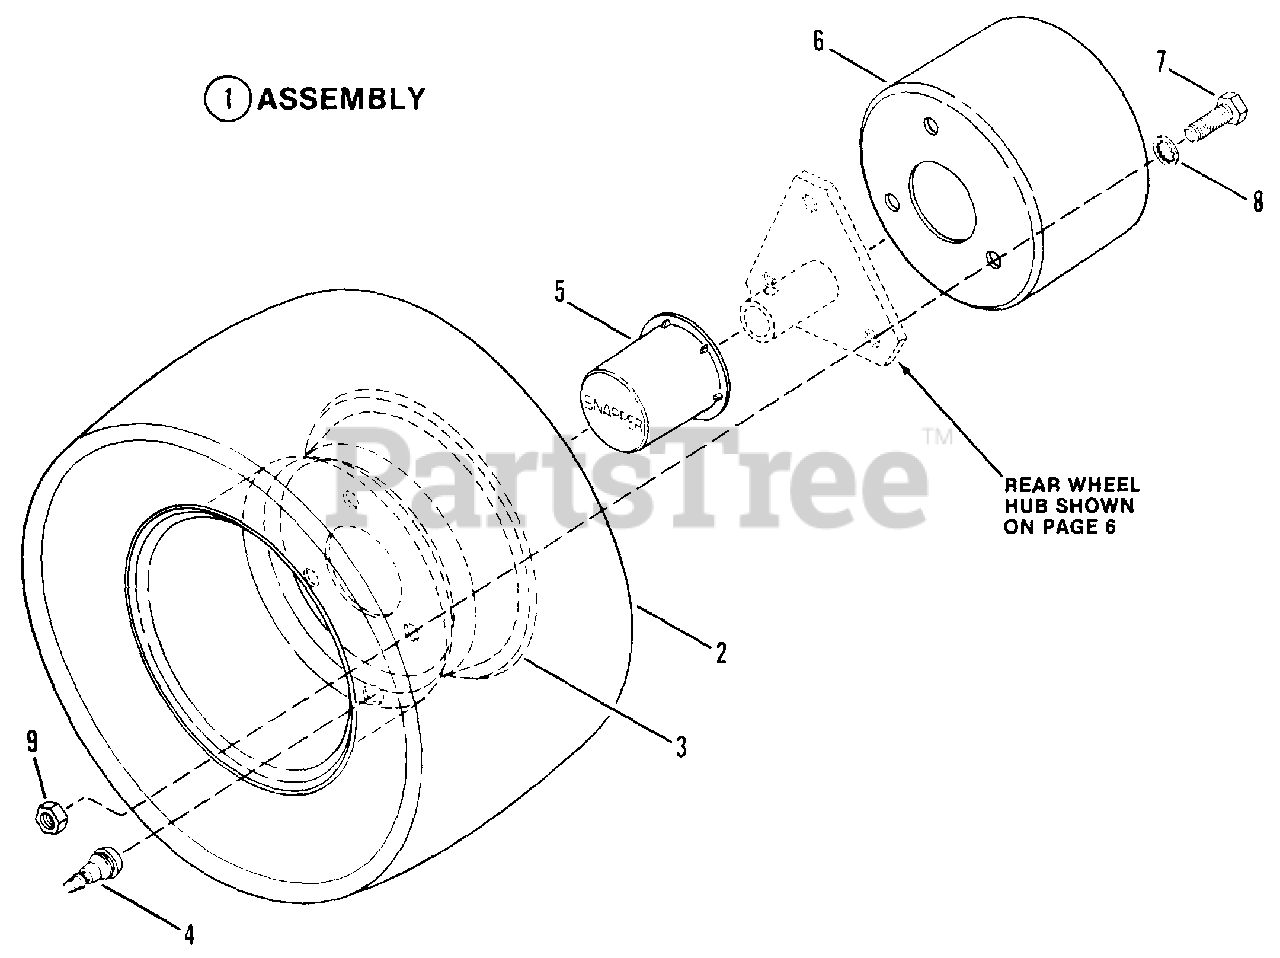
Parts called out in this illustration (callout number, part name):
1	ASSEMBLY, Rear Tire & Rim
2	TIRE, Wide, 16/6.50 x 8
3	RIM, Wide
4	VALVE, Air
5	HUB-CAP
6	BRAKE DRUM
7	SCREW, 1/2-20 x 1-1/4" Hex Head Cap
8	WASHER, 1/2" Internal Tooth Lock
9	NUT, 1/2-20 Hex
